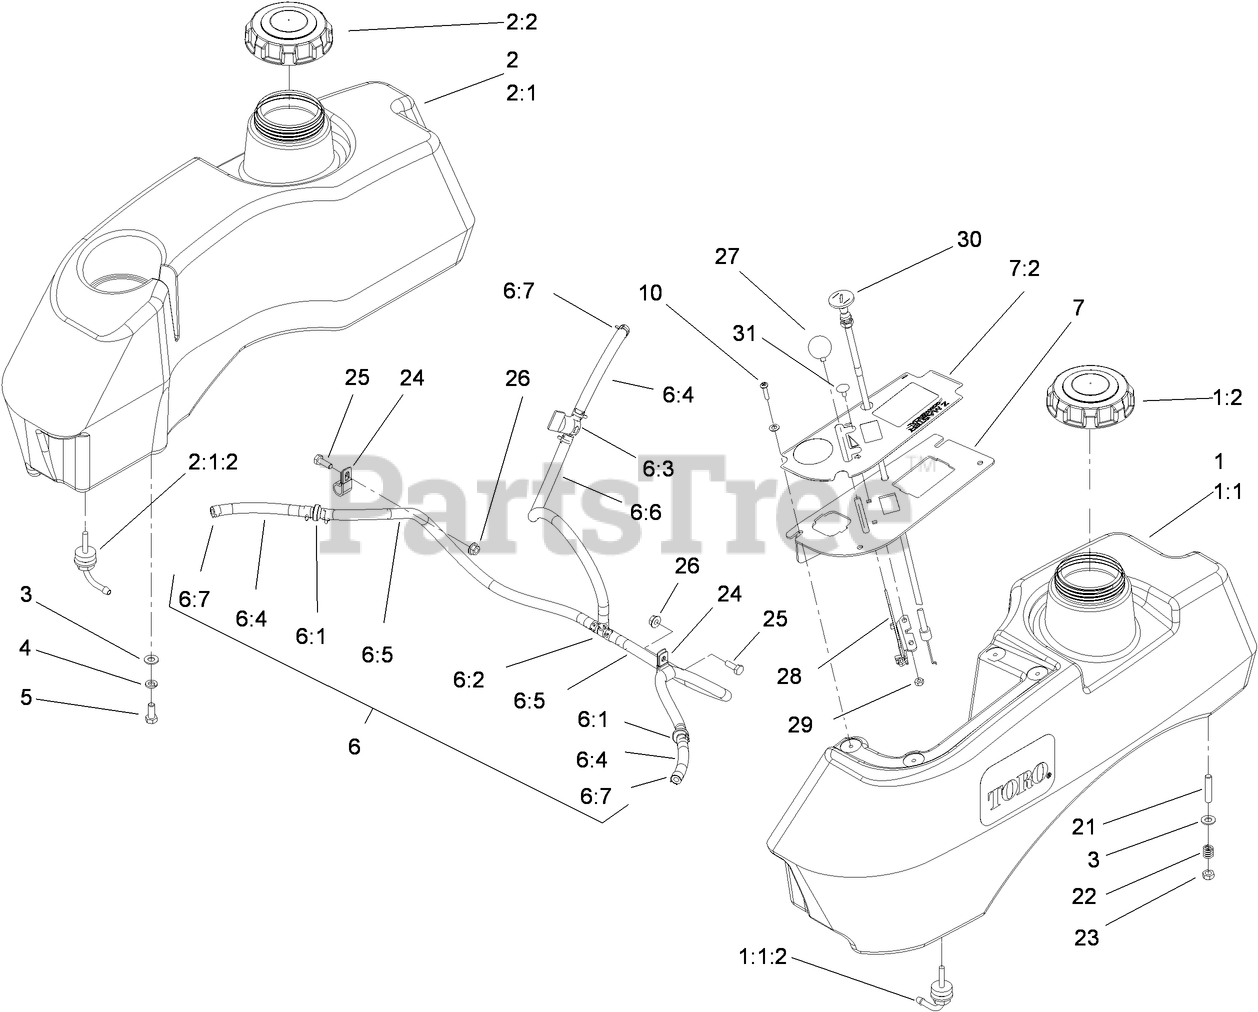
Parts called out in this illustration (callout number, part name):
1	LH FUEL TANK SERVICE KIT
1:1	LH FUEL TANK ASM
1:1:2	FITTING-FUEL, BULKHEAD
1:2	CAP-FUEL, GAS
2	RH FUEL TANK SERVICE KIT
2:1	RH FUEL TANK ASM
2:1:2	FITTING-FUEL, BULKHEAD
2:2	CAP-FUEL, GAS
3	WASHER-PLAIN
4	WASHER-LOCK
5	SCREW-HH
6	Hose-Fuel
6:1	VALVE-CHECK, FUEL
6:2	FITTING-TEE, BARBED
6:3	VALVE-FUEL
6:4	HOSE-FUEL
6:5	HOSE-FUEL
6:6	HOSE-FUEL
6:7	Clamp-Hose
7	CONTROL PANEL ASM
7:2	DECAL-PANEL, CONTROL
10	SCREW-PPH
22	SPRING-TANK, FUEL
23	NUT-LOCK, NI
24	CLIP-LOOM
25	SCREW-HH
26	NUT-HF
27	KNOB-BALL
28	THROTTLE CABLE ASM
29	NUT-LOCK, NI
30	CONTROL-CHOKE, PUSH / PULL
31	BOLT-CARR
